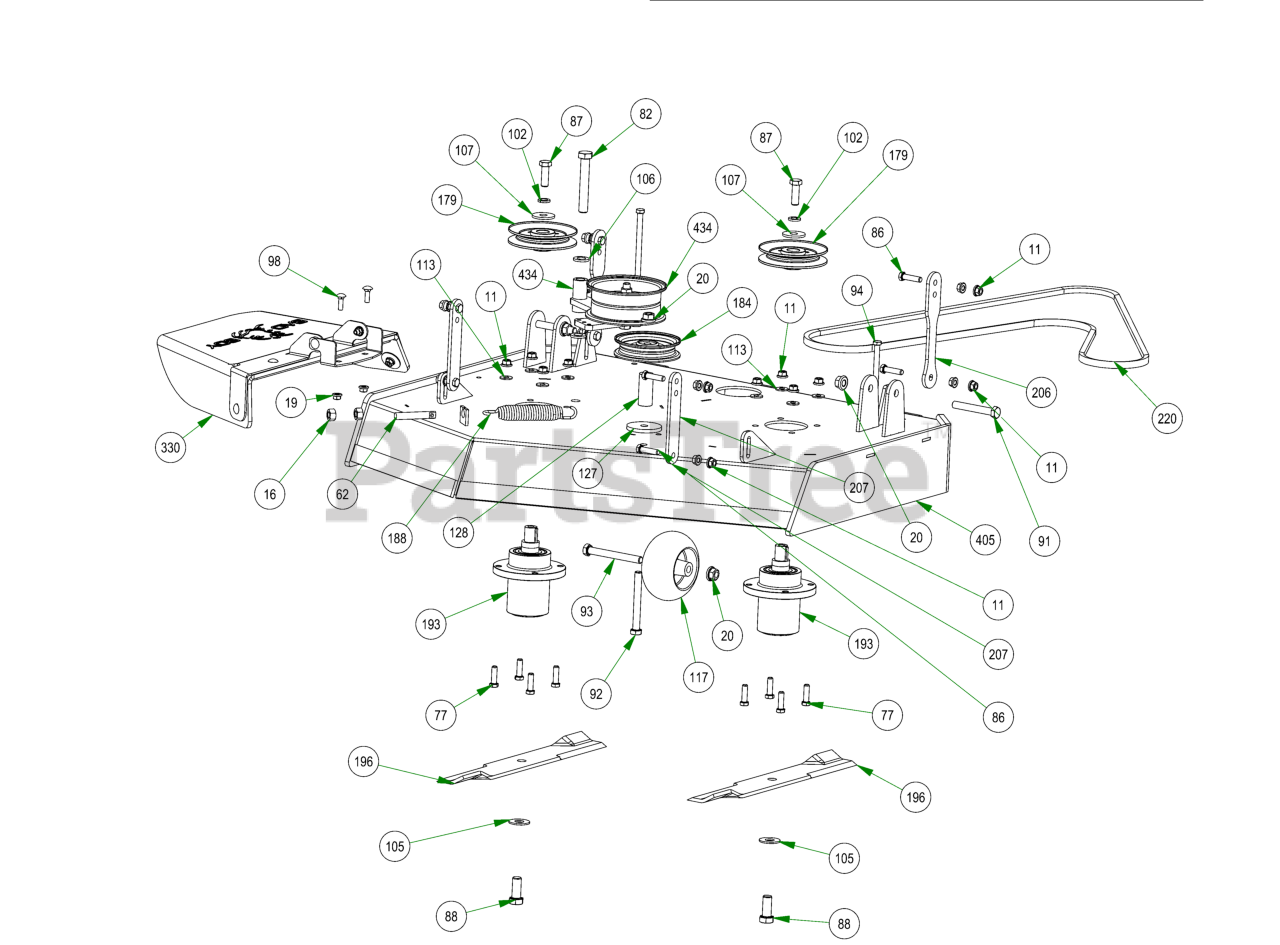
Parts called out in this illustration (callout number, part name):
10	3/8-16 HEX SERRATED FLANGE NUT HARD/ZINC
11	3/8-16 NYLON INSERT FLANGE LOCKNUT (GR.F) ZINC
13	5/8-11 NYLON INSERT JAM LOCKNUT ZINC
16	1/2-13 HEX NUT ZINC
19	5/16-18 NYLON INSERT FLANGE LOCKNUT ZINC
20	1/2-13 NYLON INSERT FLANGE LOCKNUT ZINC
62	All Thread
77	3/8-16 X 1-1/4 HEX CAP SCREW (GR.5) ZINC
82	5/8-11 X 4 HEX CAP SCREW (GR.8) ZINC YELLOW
86	3/8-16 X 1-1/2 HEX CAP SCREW (GR.5) ZINC
87	1/2-20 X 1-1/2 HEX CAP SCREW (GR.5) ZINC
88	5/8-18 X 1-1/2 HEX CAP SCREW (GR.8) ZINC YELLOW
91	1/2-13 X 3-1/2 HEX CAP SCREW (GR.5) ZINC
92	1/2-13 X 4-1/4 HEX CAP SCREW (GR.5) ZINC
93	1/2-13 X 4-1/2 HEX CAP SCREW (GR.5) ZINC
94	3/8-16 X 5-1/2 HEX CAP SCREW (GR.5) ZINC
98	5/16-18 X 1 CARRIAGE BOLT (GR.8) ZINC
102	1/2 SPLIT LOCKWASHER (GR.8) ZINC/YELLOW
105	5/8 USS FLAT WASHER (1-3/4" OD) GR.8 ZINC YELLOW
106	.635 ID X 1.120 OD X .140 THICK FLAT WASHER NYLON
107	1/2 BELLEVILLE WASHER (1-5/8 OD X .140 THK) ZINC
113	5/16 USS FLAT WASHER (7/8 OD) ZINC
117	2019 Deck Wheel
127	MZ Deck Idler Spacer
128	2019 Revolt Stationary Idle Spacer
129	36 Deck Spindle Spacer
179	MZ Deck Pulley
184	5 V Idler Pulley 1/2" Bore
188	2009 Deck/Pump Idler Spring
193	36'' Revolt Spindle Assembly
196	52" Deck Fusion Blade
206	2019 Stand-On Rear Deck Hanger
207	2019 Revolt Front Deck Hanger
220	2020 Walk-Behind 36 Deck Belt
221	3/16 X 1 SQ MACHINERY KEY 1018 STL ZINC
330	2020 36 Stand On Discharge Assembly
365	2023 MZ Stripping Kit Rubber
405	2023 36'' DECK
434	2020 36" Revolt Deck Idler Assembly
